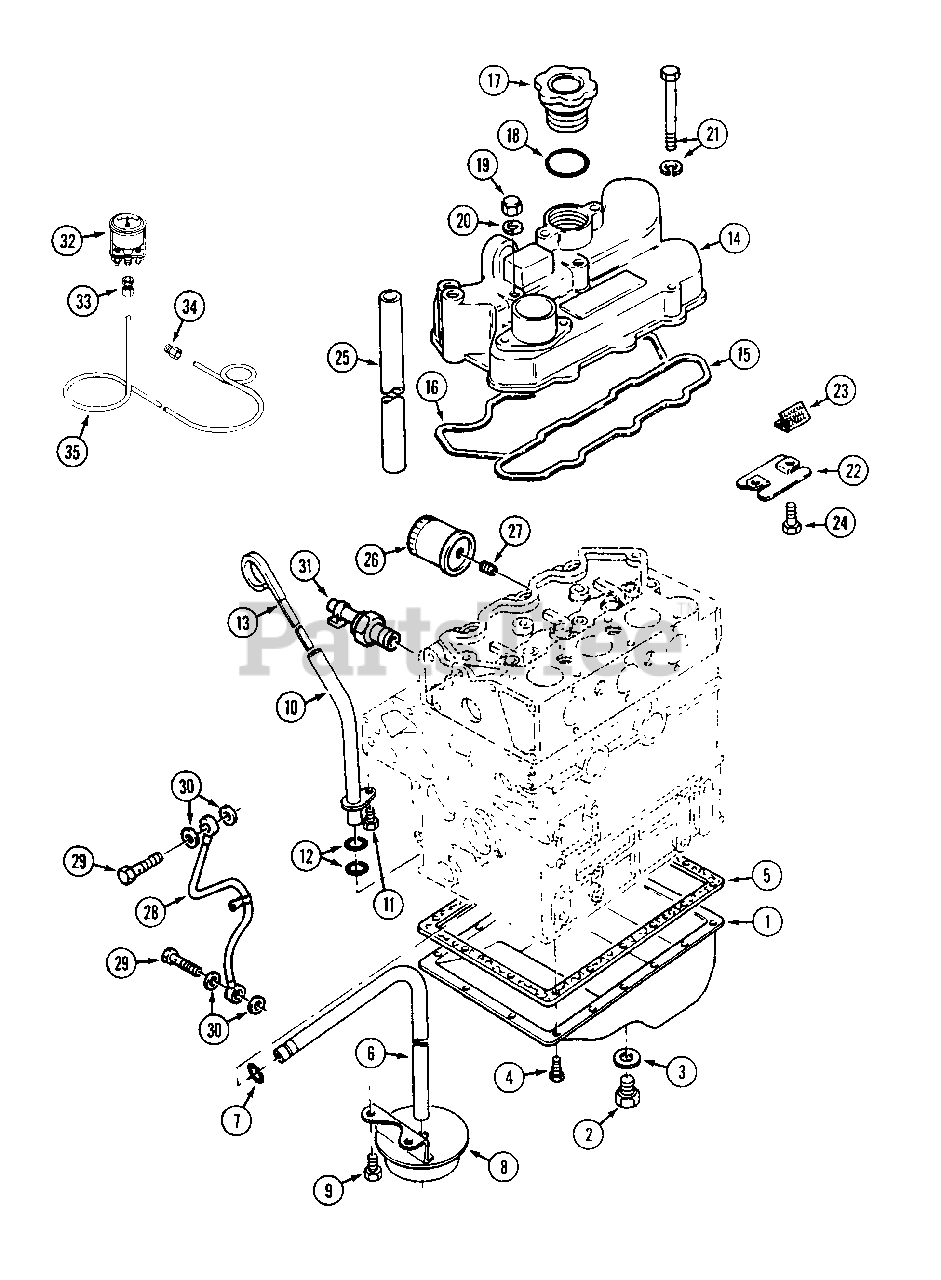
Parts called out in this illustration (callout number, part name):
1	SUMP
2	PLUG
4	SCREW
5	GASKET
6	PIPE
7	"O" RING
8	STRAINER
9	BOLT
10	TUBE
11	BOLT
12	"O" RING
13	DIPSTICK
14	COVER
15	GASKET
16	GASKET
17	CAP
18	"O" RING
19	NUT
20	WASHER
21	SCREW
22	PLATE
23	GAUZE
24	BOLT
25	HOSE
27	CONNECTOR
28	PIPE
29	BOLT
30	WASHER
31	SWITCH - oil pressure
32	GAGE - pressure, oil
33	FITTING - 1/8" tube
34	FITTING - 1/8" x 1/8"
35	TUBE - 1/8" x 58" copper
